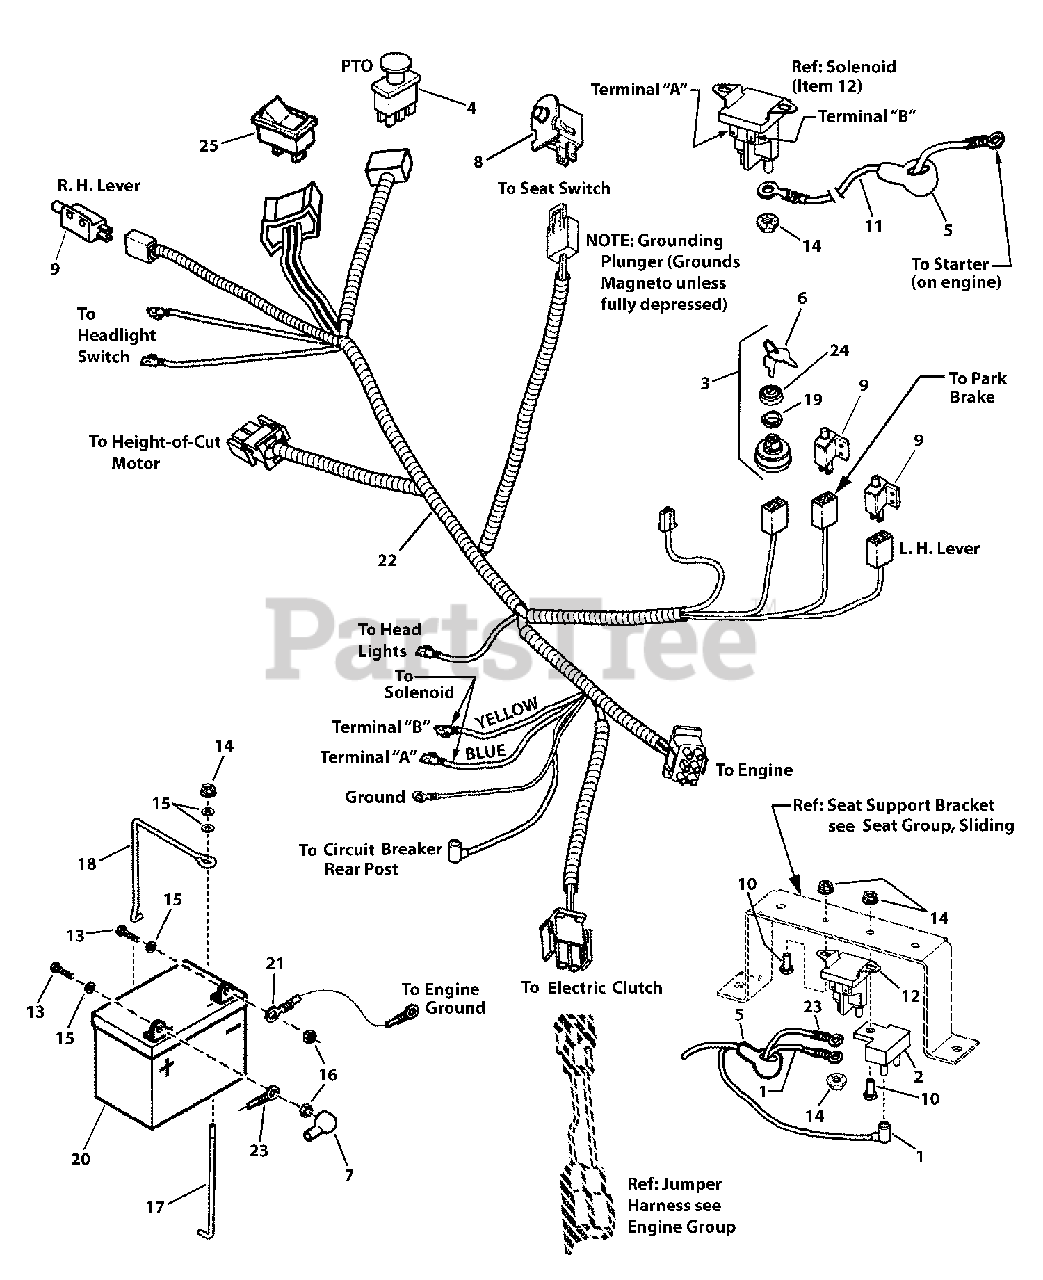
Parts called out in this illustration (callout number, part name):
1	WIRE, 12 Gage, 8" Red
2	BREAKER, Circuit 12 Volt 20 Amps w/Tab
3	SWITCH ASSEMBLY, Ignition Indak No Keys/Hdwr
4	SWITCH, PTO Push/Pull Symbols
5	COVER, Terminal Red Vinyl
6	KEYS, BLISTER PK KIDS+MWRS DON'T MIX, DOM
7	BOOT, Insulator, Battery Terminal PVC Red
8	SWITCH, Seat, Push Button (NC) (gray)
9	SWITCH, DPDT (NC/NO) (Gray)
10	SCREW, 1/4-20 x 5/8" Hex Head Cap, GR 5 YZ
11	WIRE, Negative, 8 Gage, 14, Black
12	SOLENOID, Super Trombetta, 2 Terminal
13	SCREW, 1/4-20 x 5/8" Hex Head Cap, GR 5 YZ
14	NUT, 1/4-20 Hex Flange Lock, YZ
15	WASHER, 1/4" Flat, YZ
16	NUT, 1/4-20 Hex Center Lock, GR 5 BZ
17	HOLD DOWN, Battery
18	BRACKET, Battery
19	NUT, 5/8-32, E-Start
20	BATTERY, 12 Volt, 230 CCA
21	CABLE, Battery, Negative, 8 Gage, 20", Black
22	HARNESS, Wiring, RZT
23	CABLE, Battery, Positive, 8 Gage, Red
24	CAP, Ignition Switch
25	SWITCH, Rocker Electric Height-Of-Cut
